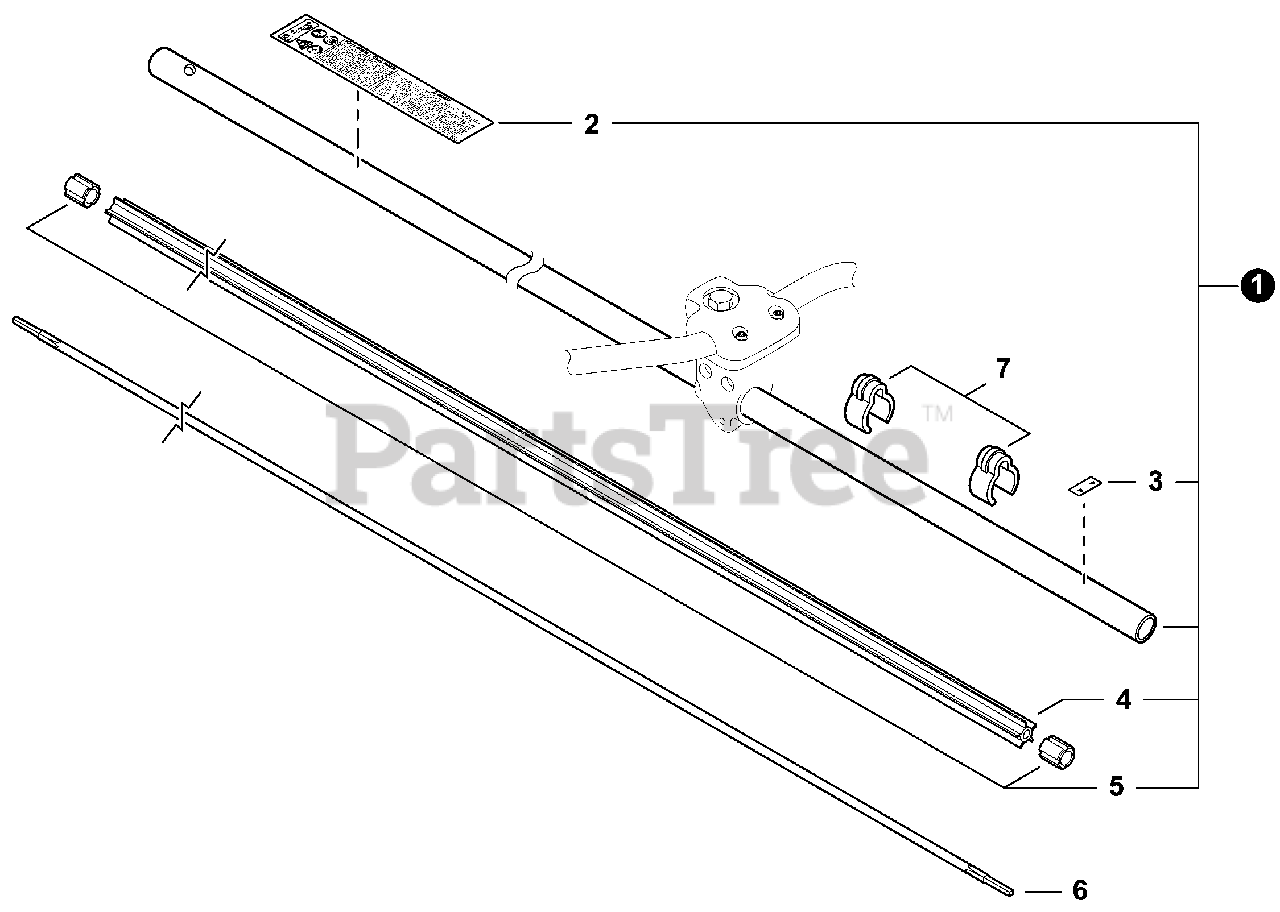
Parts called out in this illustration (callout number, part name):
1	MAIN PIPE ASSY
2	LABEL, CAUTION
3	LABEL - ALIGNMENT
4	LINER, FLEXIBLE 21.6×1420
6	DRIVESHAFT - FLEXIBLE
7	CLIP, CABLE 25 MM
